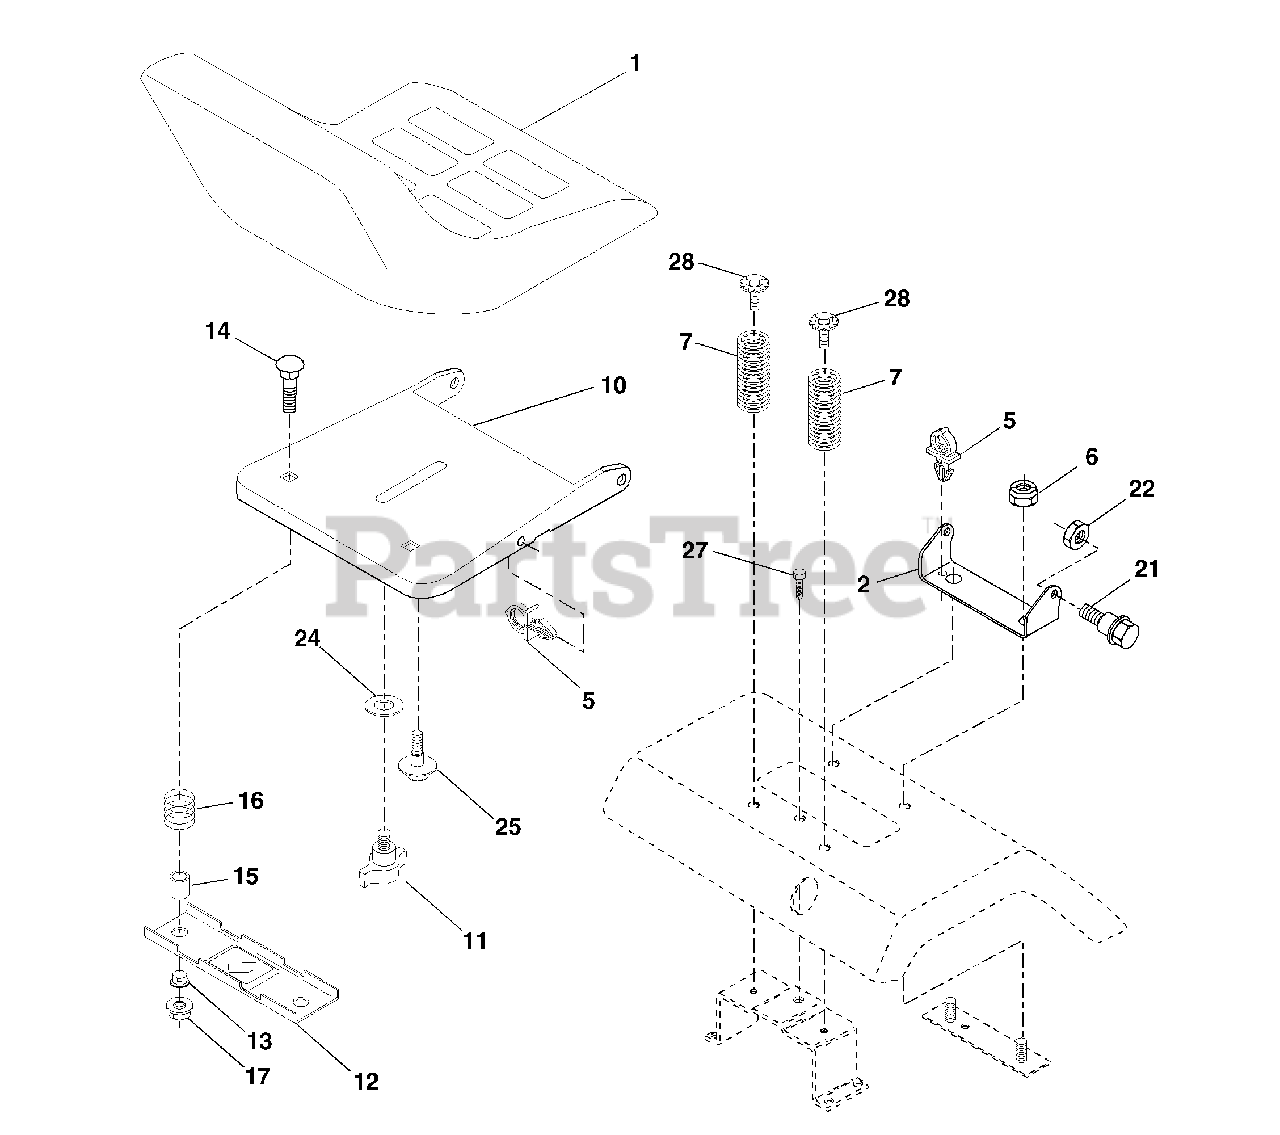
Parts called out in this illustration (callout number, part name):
1	Seat
2	Bracket Pivot Seat 8 720
3	Bolt Fin Hex 3/8-16unc X 1
4	Washer 13/32 X 1 X 10 Ga
5	Clip Push-In
6	Nut Hex w/Ins. 3/8-16 Unc
7	Spring Seat Cprsn 2 250 Blk Zi
8	Screw Thdrol 3/8-16 X 1-1/2
9	Washer 13/32 X 1 X 14 Ga.
10	Pan Seat
11	Knob Seat Adj Wingnut
12	Bracket Mounting Switch
13	Bushing Snap Blk Nyl 50 Id
14	Bolt Rdhd Sqnk 1/4-20x1-1/2
15	Spacer Split 28 x .88 Zinc
16	Spring Cprsn Plate
17	Nut Lock 1/4 Lge Flg Gr 5 Zinc
18	Cap Spring Seat
21	Bolt Shoulder 5/16-18 Unc
22	Nut Hex Lock W/Ins 5/16-18
24	Washer 17/32 X 1 -3/16 X 12 Ga.
25	Bolt Shoulder 5/16-18 X 62
27	Screw Thdrol 3/8-16 x 1/2 Ty-tt
28	Bolt 5/16-18unc x 3/4 W/Sens
